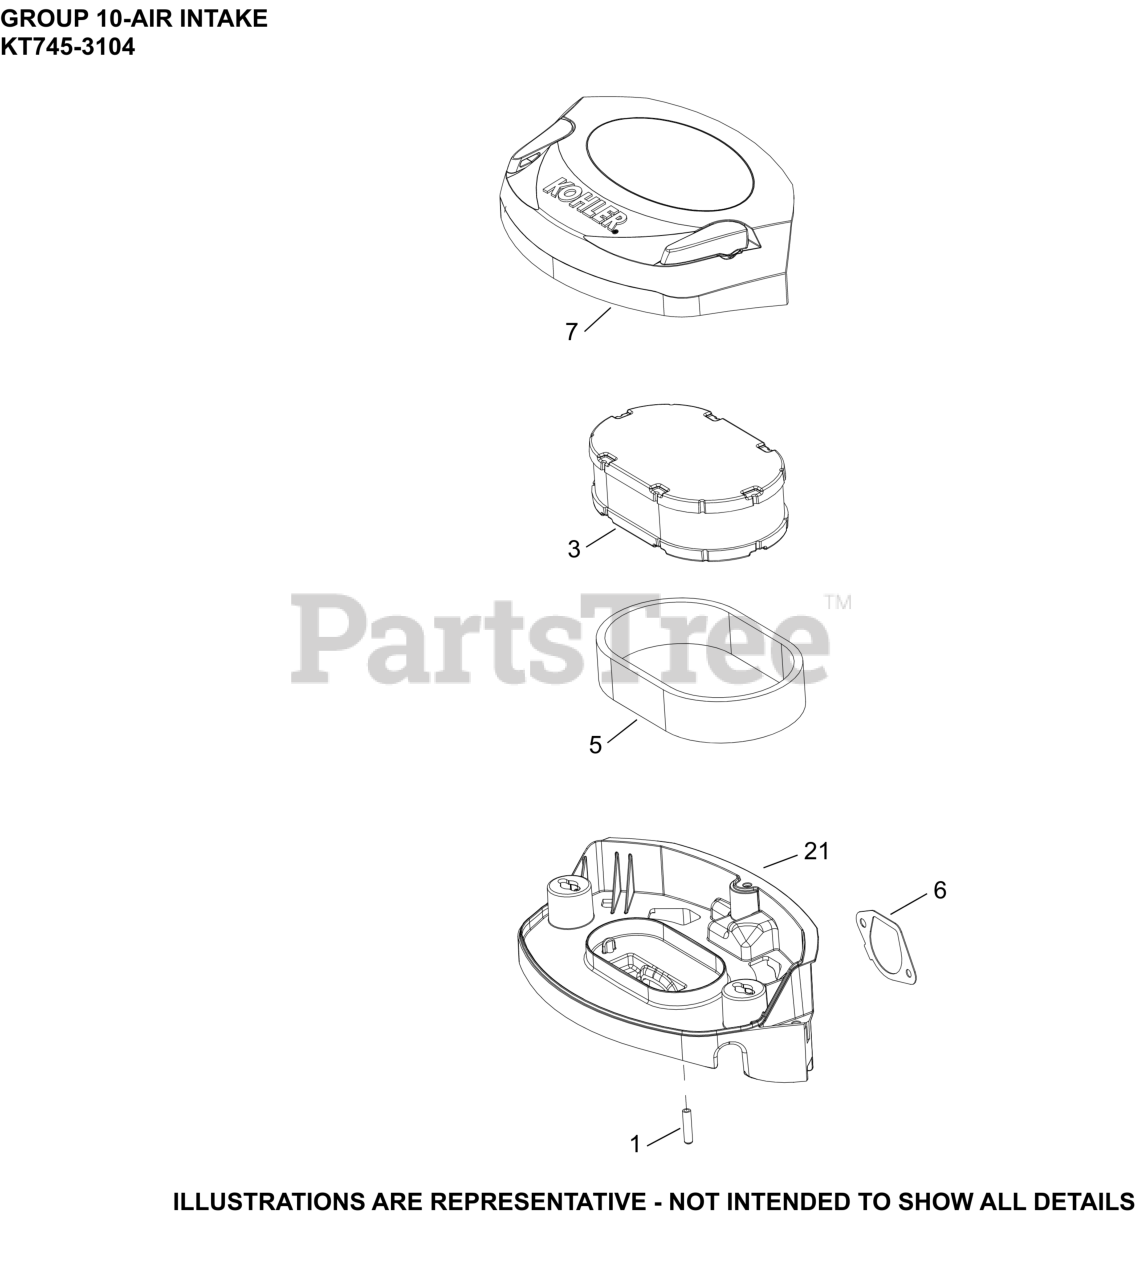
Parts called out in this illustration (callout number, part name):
1	CAP, MASKING
3	ELEMENT, AIR FILTER
5	ELEMENT, PRE-CLEANER
6	GASKET, AIR CLEANER BASE
7	COVER ASSEMBLY, AIR CLEANER
21	BASE ASSEMBLY, AIR CLEANER
